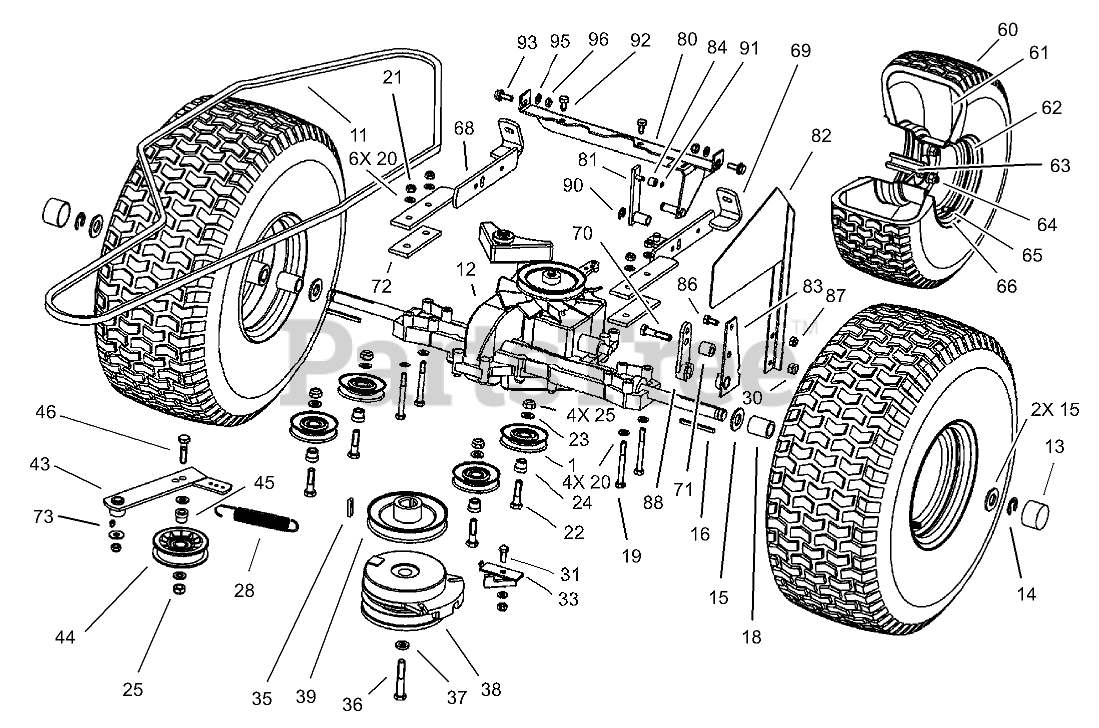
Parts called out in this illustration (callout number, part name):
1	PULLEY-IDLER
11	V-BELT-TRACTION
12	TRANSMISSION
13	CAP-HUB
14	CLIP-SPRING
15	WASHER
16	KEY-SQUARE
18	SPACER-AXLE
19	SCREW-HH
20	WASHER-PLAIN
21	NUT-LOCK, NI
22	SCREW-HH
23	WASHER-FLAT
24	BUSHING-IDLER
25	NUT-LOCK, NI
28	SPRING
30	NUT-LOCK, NI
31	SCREW-HH
33	RETAINER
35	KEY-SQUARE
36	SCREW-HH
37	WASHER-SPRING, BELLEVILLE
38	CLUTCH-ELECTRIC
39	PULLEY-ENGINE
43	ARM-IDLER
44	PULLEY-IDLER
45	BUSHING-IDLER
46	SCREW-HH
60	TIRE-TURF SAVER 4 PLY
62	WHEEL ASM
63	HUB-WHEEL
64	NUT-WHEEL
65	Valve-Tire
68	Bracket-Right
69	Bracket-Left
70	SCREW-HH
71	SLEEVE
72	Plate-Reinforcing
73	FITTING-GREASE
80	Bar ASM
81	Arm-Switch
82	ARM-CONTROL, CRUISE
84	Roller
86	SCREW-HH
87	NUT-LOCK, NI
88	ARM-TRANSAXLE
90	Stirrup
91	STIRRUP
92	SCREW-THREAD FORMING
93	SCREW-HEX
95	WASHER-PLAIN
96	NUT-LOCK, NI
